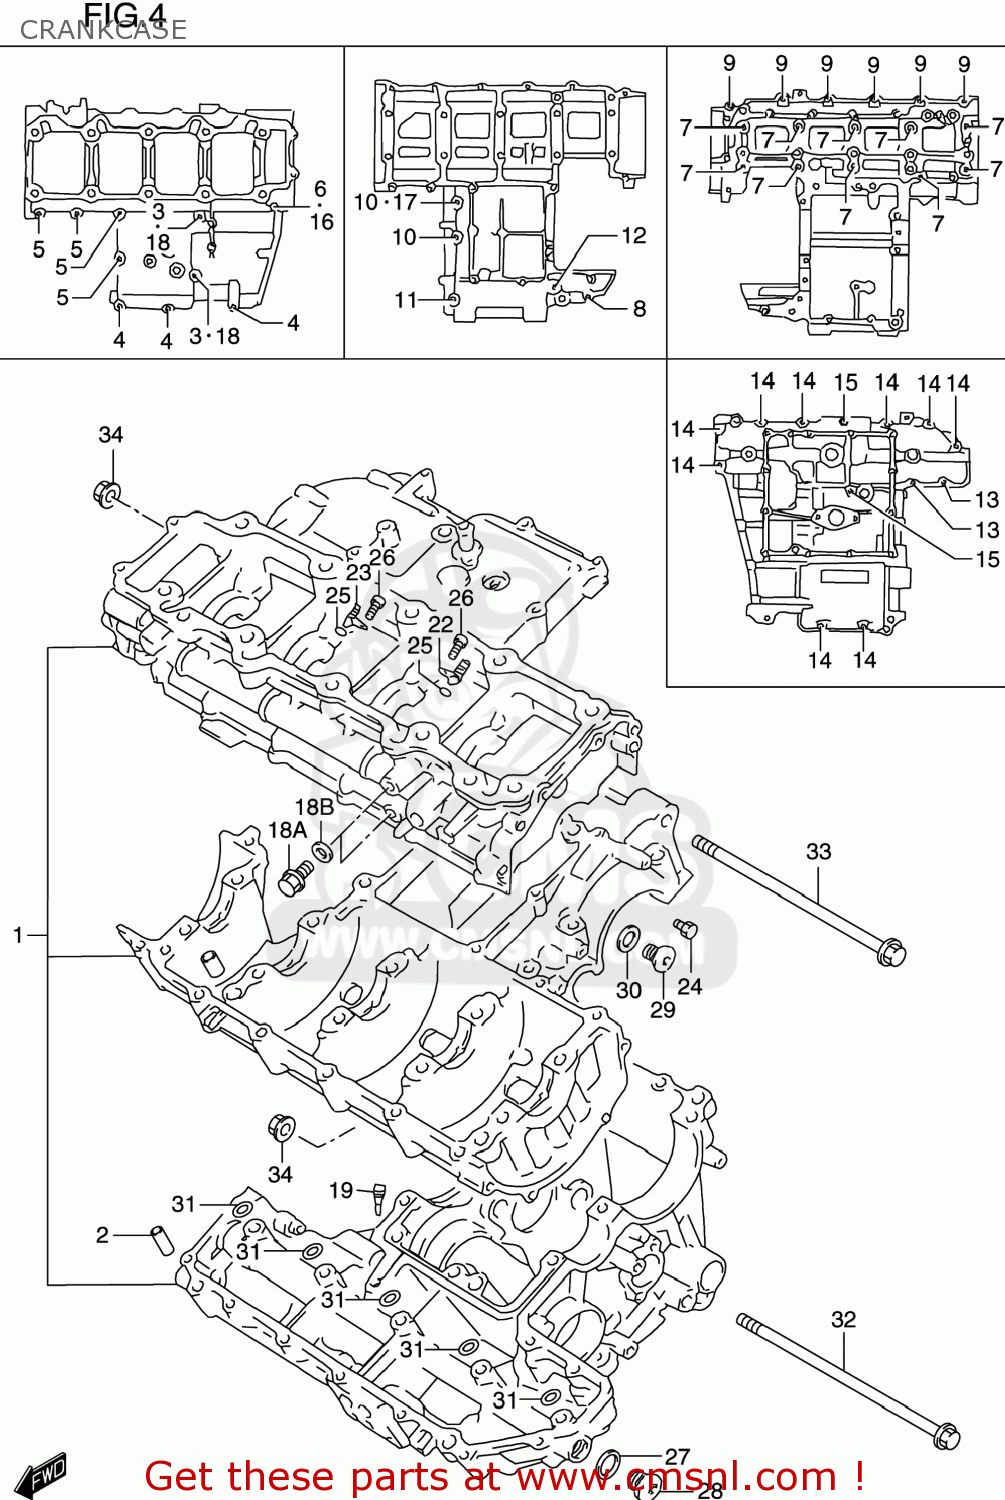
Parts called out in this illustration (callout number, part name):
1	CRANKCASE SET
2	PIN,CRANKCASE
3	BOLT(8X120)
4	BOLT
5	BOLT
6	BOLT
7	BOLT(9X95)
8	BOLT
9	BOLT
10	BOLT
11	BOLT
12	BOLT
13	BOLT,G/S SWITC
14	BOLT
15	BOLT
16	GASKET(5.8X11X1.2) (NAS)
17	GASKET(8.2X14X1) (NAS)
18	GASKET(8.2X14X1) (NAS)
18A	BOLT
18B	GASKET(5.8X13X1.2) (NAS)
19	JET(140)
20	BEARING,CRANK THRUST(GREEN)
21	BEARING,CRANK THRUST(RED)
22	JET,PISTON COOLINGR
23	JET,PISTON COOLING
24	JET,MAGNETO COOLING
25	O RING(D:1.2,ID:4)
26	BOLT(6X12)
27	GASKET(16X22X2) (NAS)
28	PLUG,16X8
29	PLUG,14X12
30	GASKET(13.8X18.8X4.8) (NAS)
31	O RING(D:1.9,ID:7.8)
32	BOLT(10X205)
33	BOLT(10X185)
34	NUT
